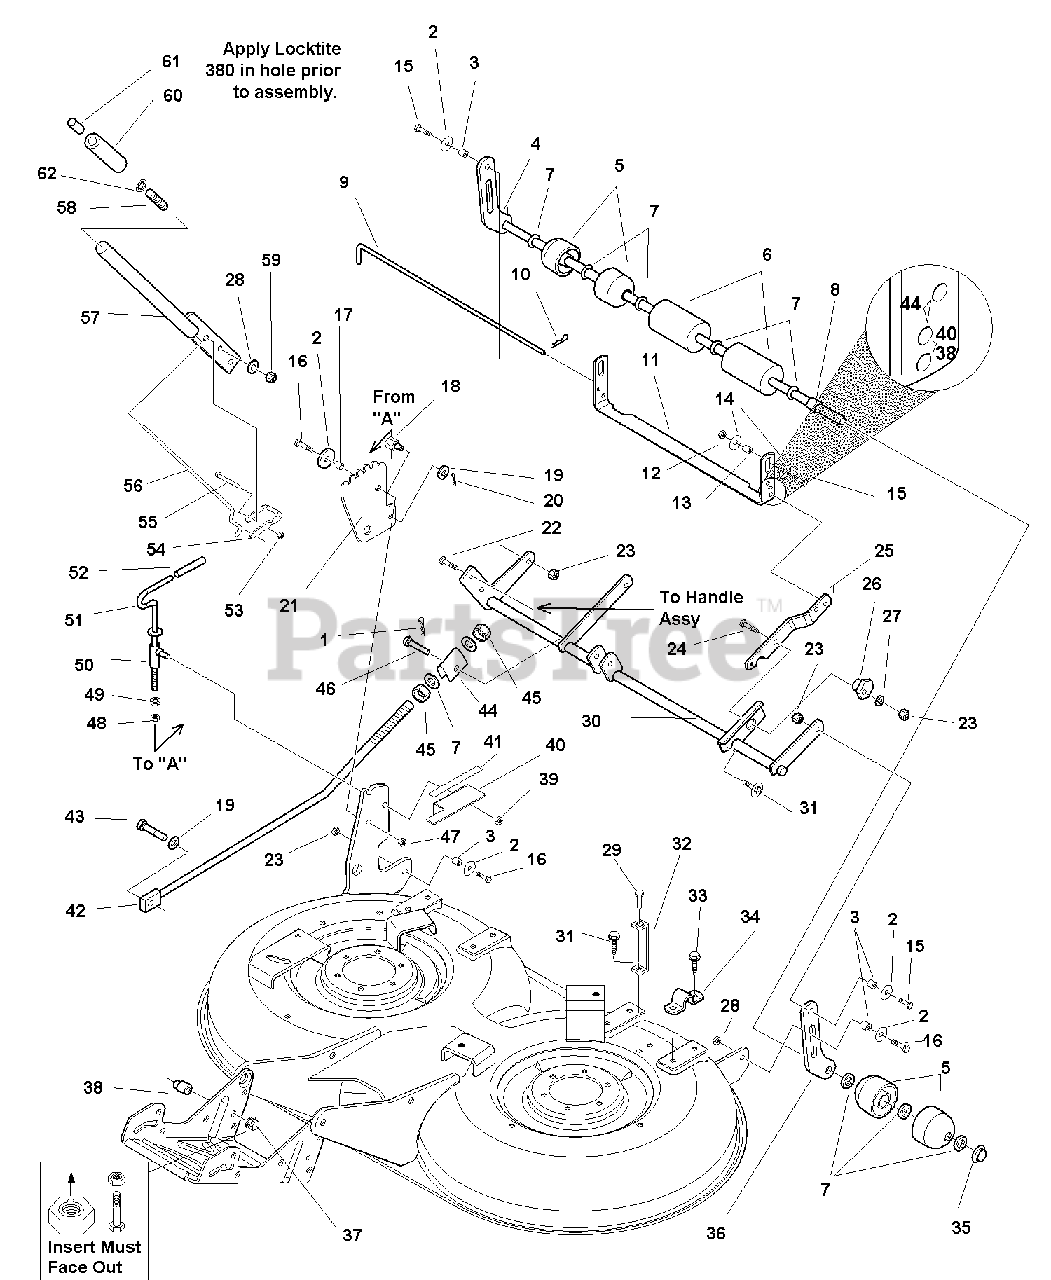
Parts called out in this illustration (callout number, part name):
1	CLIP, Hair Pin, 1/8 x 1
2	WASHER, 5/16
4	SHAFT & BAR ASSEMBLY, 40" Roller
7	WASHER, 5/8
9	ROD, Transport
10	CLIP, Hair Pin
11	U-BRACKET
12	NUT, Hex Centerlock 5/16-18
14	WASHER, 5/16
15	CAPSCREW, Hex Head, 5/16-18 x 1-1/4
16	CAPSCREW, Taptite Hex Washer Head, 5/16-18 x 1
18	PIVOT, 3/4 Hex
19	WASHER, 3/8
20	PIN, Cotter
21	BRACKET, Adjusting
22	CARRIAGE BOLT, 5/16-18 x 1
23	NUT, Hex Flange Lock, 5/16-18
24	CARRIAGE BOLT, 5/16-18 x 1-1/4
26	CAM, Eccentric 1 1/8 Hex
27	WASHER, 5/16
28	LOCKWASHER, 5/16
29	FASTENER, Panel
30	SHAFT ASSEMBLY, Rocker
31	CAPSCREW, Hex Head, Taptite 5/16-18 x 7/8
33	CAPSCREW, Taptite Hex Washer Head, 5/16-18 x 3/4
34	STRAP, Roller Support
35	NUT, Push 5/8
36	BAR, Roller
37	NUT, Hex Aluminum Lock, 3/8-16
39	NUT, Hex Centerlock 3/8-16
40	BRACKET, Height of Cut
41	DECAL, Height of Cut
42	ROD, Adjustment
43	CAPSCREW, Hex Head, 3/8-16 x 1-3/4
44	TRUNNION, Rod
45	NUT, Hex, 5/8-11
46	PIN
47	NUT, Hex Flange Lock, 5/16-18
48	NUT, Hex Jam 3/8-16
49	NUT, Hex Flange, 3/8-16
50	GUIDE ASSEMBLY, Rod
51	ROD & WASHER ASSEMBLY, Adjust Handle
52	GRIP, Black Vinyl For Rod
53	NUT, Hex Lock Esna Light, 1/4-20
54	LATCH, 5/16 WIRE
55	CAPSCREW, Hex Head, 1/4-20 x 2-1/4
57	HANDLE ASSEMBLY, Lift
58	SPRING, Compression
59	NUT, Hex, 5/16-18
60	GRIP, Black Soft for Rod
61	BUTTON, Black Nylon for Rod
62	PUSH NUT, 1/4
